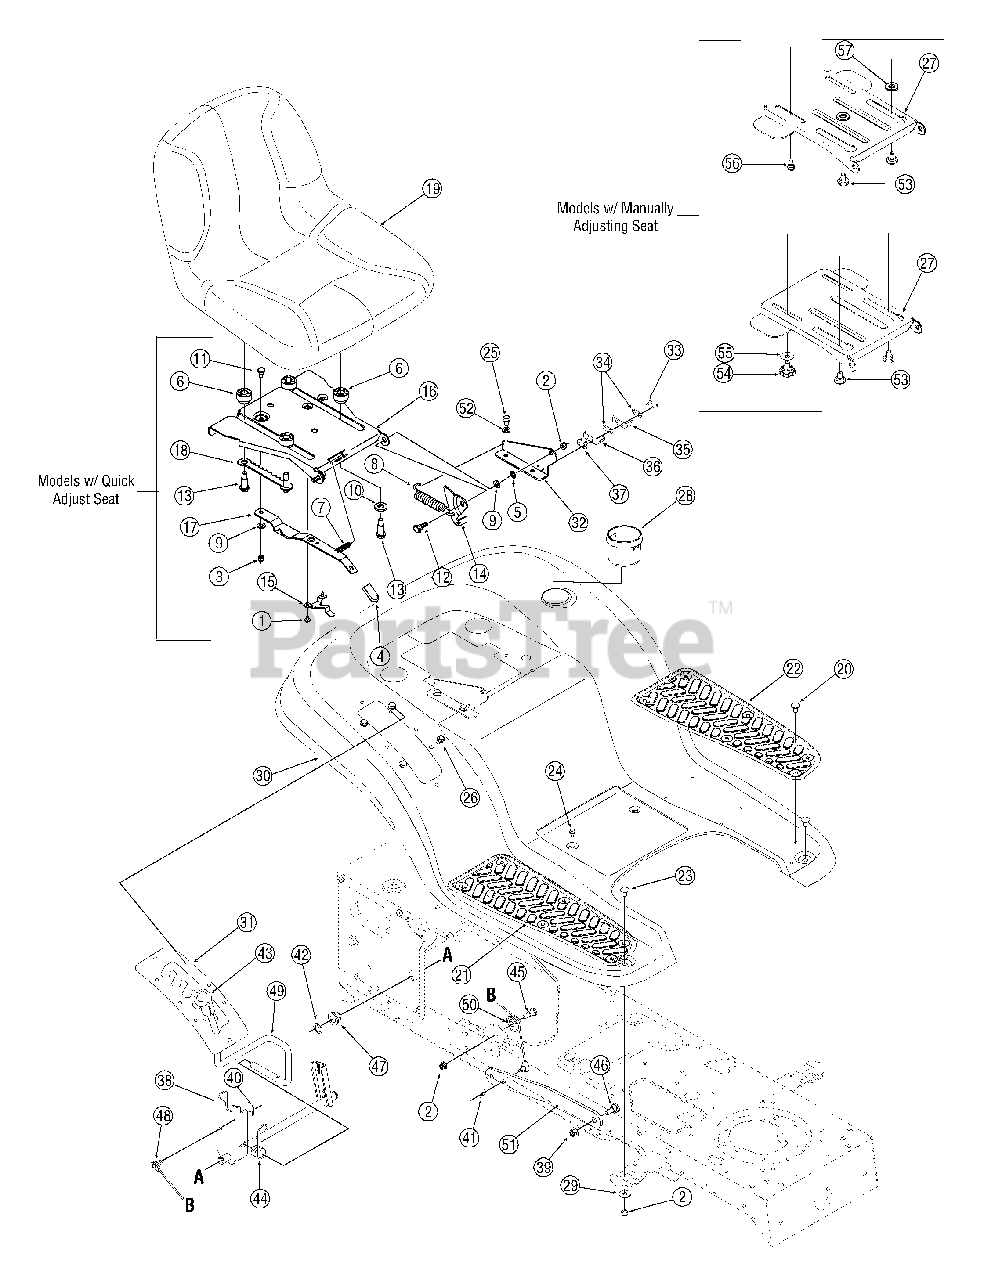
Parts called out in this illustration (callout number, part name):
1	Screw, #10-16 x.375
2	Nut, Flange Lock, 5/16-18, Gr F, Nylon
3	Nut, Flange Lock, 1/4-20
4	Seat Adjuster Grip
5	Nut, Speed,.3125 ID
6	Spacer
7	Compression Spring,.41 x 1.5
8	Spring, Extension,.84 Dia. x 4.6
9	Wash, Flat,.344 x.688 x.065
10	Wash, Flat,.531x 1.062 x.134
11	Screw, Shoulder,.340 x.285,1/4-20
12	Screw, Shoulder,.437 x.268, 5/16-18
13	Screw, Shoulder,.50 x.925, 3/8-16
14	Seat Bracket, Lift
15	Seat Stop
18	Seat Adjustment Selector
19	High Back Seat
20	Ratchet Clip
21	RH Foot Pad, Rubber
22	LH Foot Pad, Rubber
23	Bolt, Carriage, 5/16-18,.750, Gr1
24	Screw, 1/4-20, 0.500
25	Screw, 5/16-12, 0.750
26	Screw, 5/16-18 x.750
28	Cup Holder
29	Washer, Flat,.344 x 1.0 x.063
33	Screw, #8-18 x.50
34	Plate, Insulator
35	Spring Switch, Outer
36	Spring Switch, Inner
37	Plate, Insulator Boss
39	Nut, Flange Lock, 3/8-16, Gr F, Nylon
40	Pin, Cotter,.072 Dia. x 1.13
41	Pin, Cotter, 3/32, 1.0
42	Ring, E Type,.625 Dia.
43	Grip, Handle, 1/2
44	Spring, Torsion
45	Screw, 5/16-18 x.620 Gr2
46	Screw, Shld,.50 x.27, 3/8-16
47	Bearing, Hex Flange
48	Cable, Lift, 16.16
49	Handle, Lift
50	Pulley, Roller
52	Lock Washer, 5/16
53	Shoulder Screw
54	Knob, 3/8-16
55	Flat Washer,.406 x 1.00 x.030
56	Hex Head Washer Screw, 3/8-16 x.625
57	Thrust Washer,.635 x 1.26 x.06
